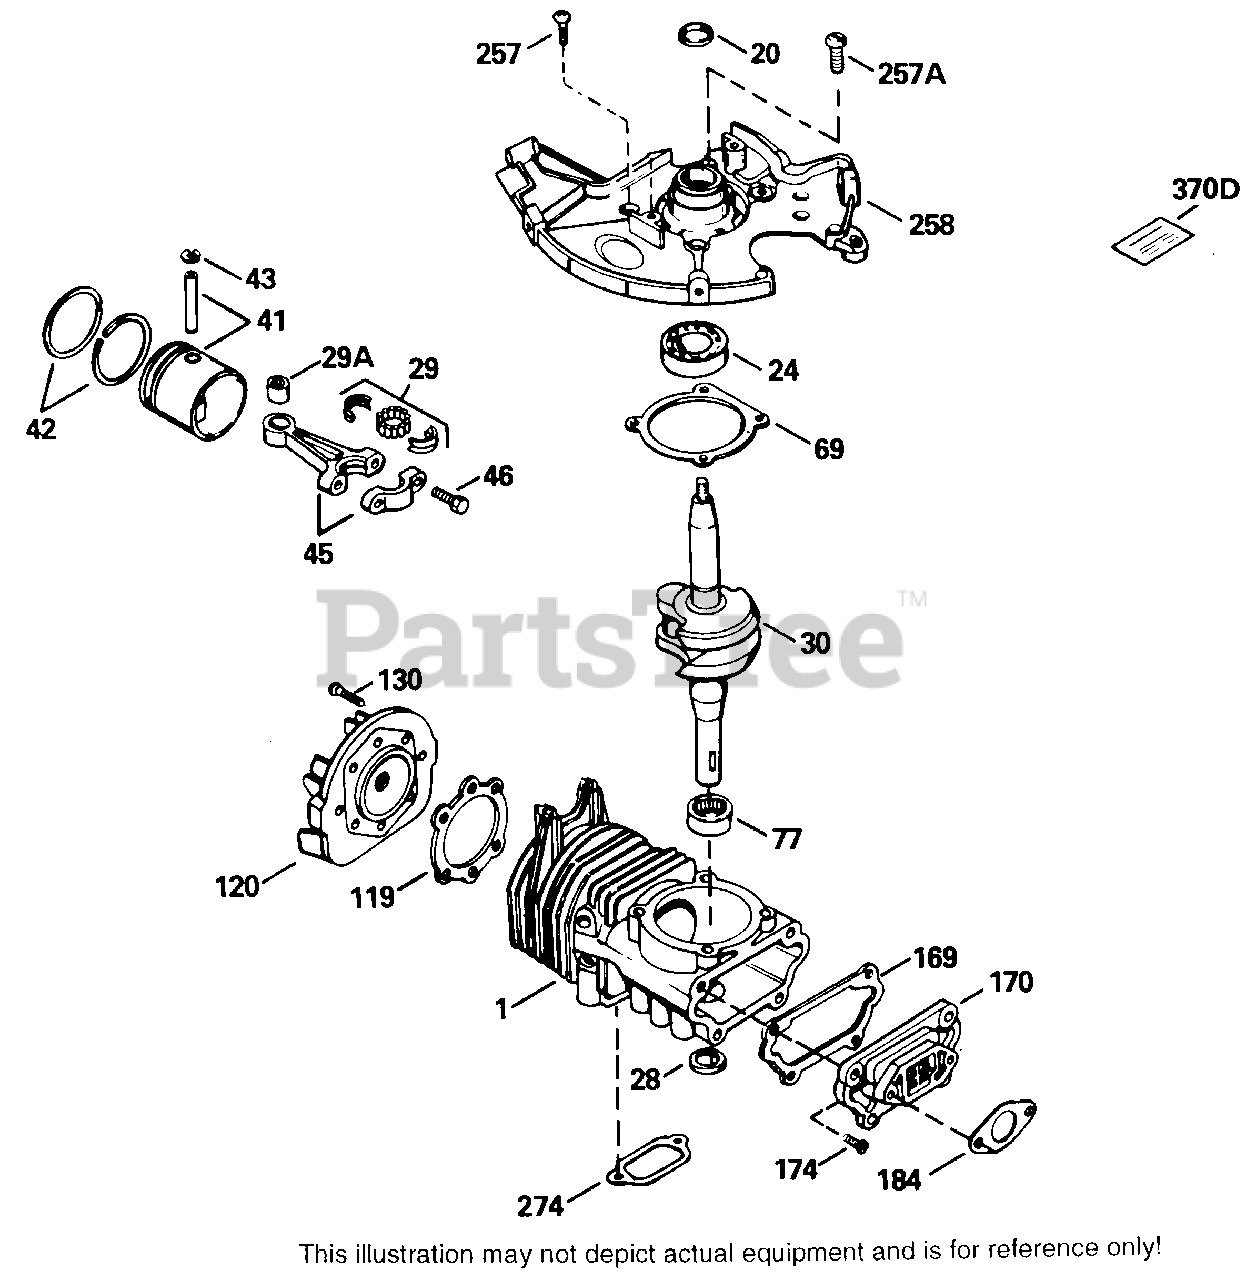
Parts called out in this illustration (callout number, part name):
1	"Cylinder Order SB if replacement isre q.
20	Seal, Crankshaft
24	Bearing, Ball
28	Oil Seal
29	Bearing & Liner Set, Needle
29A	Bearing, Cartridge
30	Crankshaft
41	Piston & Pin Assy. (Incl. 43)
42	Ring Set, Piston
43	Ring, Piston pin retaining
45	Rod Assy., Connecting Incl. 29, 29A& 46
46	Screw, Connecting rod
69	Gasket, Housing base
77	Bearing, Cartridge
119	Gasket, Cylinder head
120	Cylinder Head
130	Screw, Torx T-30, 1/4-20 x 3/4"
169	Gasket, Reed plate
170	Plate Assy., Reed
174	Screw, Torx T-25, 10-24 x 1/2"
184	Gasket, Carburetor
257	Screw, Torx T-30, 1/4-20 x 5/8"
257A	Screw, Torx 1/4-20 x 1/2"
258	Housing Base (Incl. 20)
274	Gasket, Exhaust
370D	Decal, Warning
